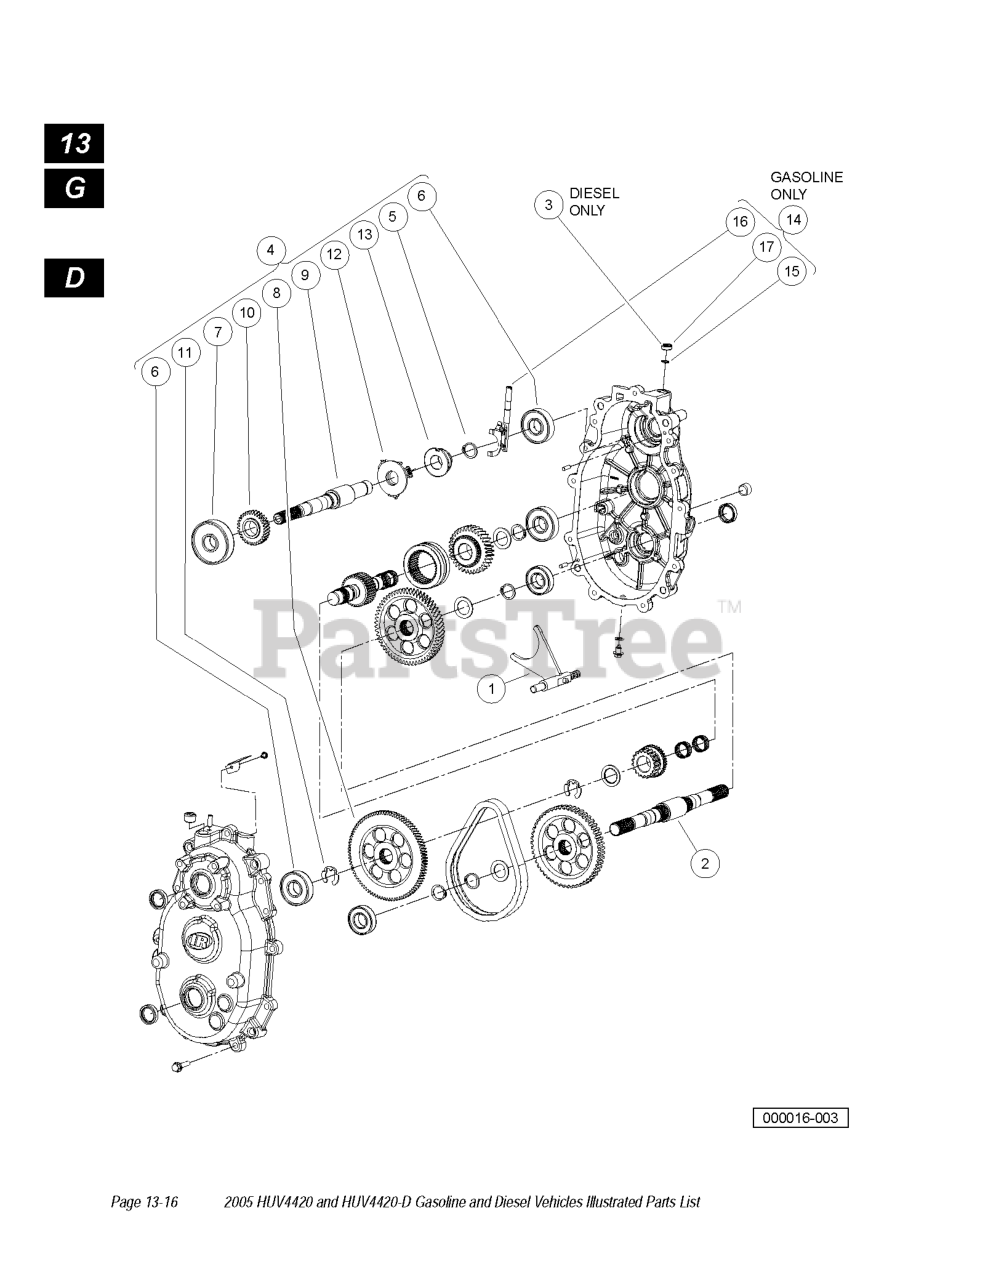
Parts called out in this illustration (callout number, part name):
1	FORK, WA, TRANS
2	SHAFT, OUTPUT
3	PLUG, 19MM
4	KIT-INPUT SHAFT REPAIR
5	RING, RETAINING, BASIC EXTERNA
6	BEARING, BALL, 6305 C3
7	BEARING, BALL, 6405 C3
11	RING, RETAINING, E-RING, PO-10
14	KIT-GOVERNOR SHAFT REPAIR
16	ASSY, GOVERNOR ARM
17	SEAL, DUAL LIP
